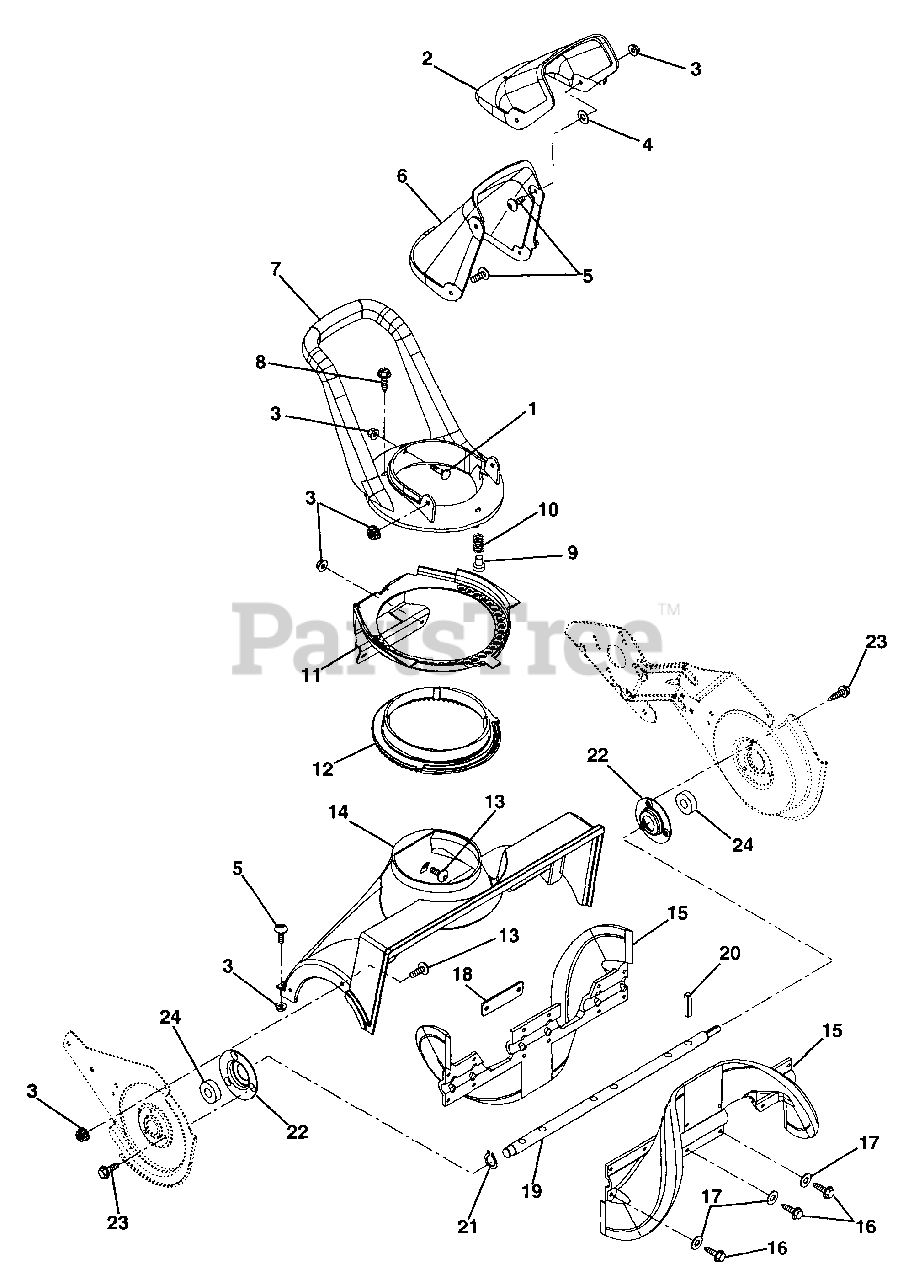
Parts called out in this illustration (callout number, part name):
1	@BLT-RDHDSQNK .25-20X.75 G5YZ
2	DEFLECTOR-DISCHARGE CHUTE ASSY
3	NUT-LK-FLG .250-20 PL BLK
4	WSHR-FL-RBR .31X1.25X.06
5	SCR-MCH .25-20X.75 TXTR YWZC
6	CHUTE-DISCHARGE ASSY
8	SCR TAP 8-18X1.50 SL HWH PL B
9	RVT- .250 X 1.125 TRUSS YWZC
10	SG-COMP .045X.360X1.75 WLD12.5
11	BRKT-DISCHARGE CHUTE ROTATION
12	GEAR-DISCHARGE CHUTE SEGMENT
13	SCR-MCH .25-20X.50 TXTR PL
14	HOUSING-IMPELLER ASSY
15	IMPELLER HALF
16	@SCR-TAP .25-20X1.00 HWH TR YZ
17	WSHR-FL-STL .281X1.000X.063
18	PLATE-BOLT,SELF-TAPPING
19	SHAFT-IMPELLER
20	PIN-ROLL .250X1.75 ZINC PL
21	RG-RTNG-EXT .672X.035
22	CUP-BRG
23	@SCR-TAP .25-20X.50 HWH TR YWZ
24	BRG-BALL .669X1.575X.47 (6203)
